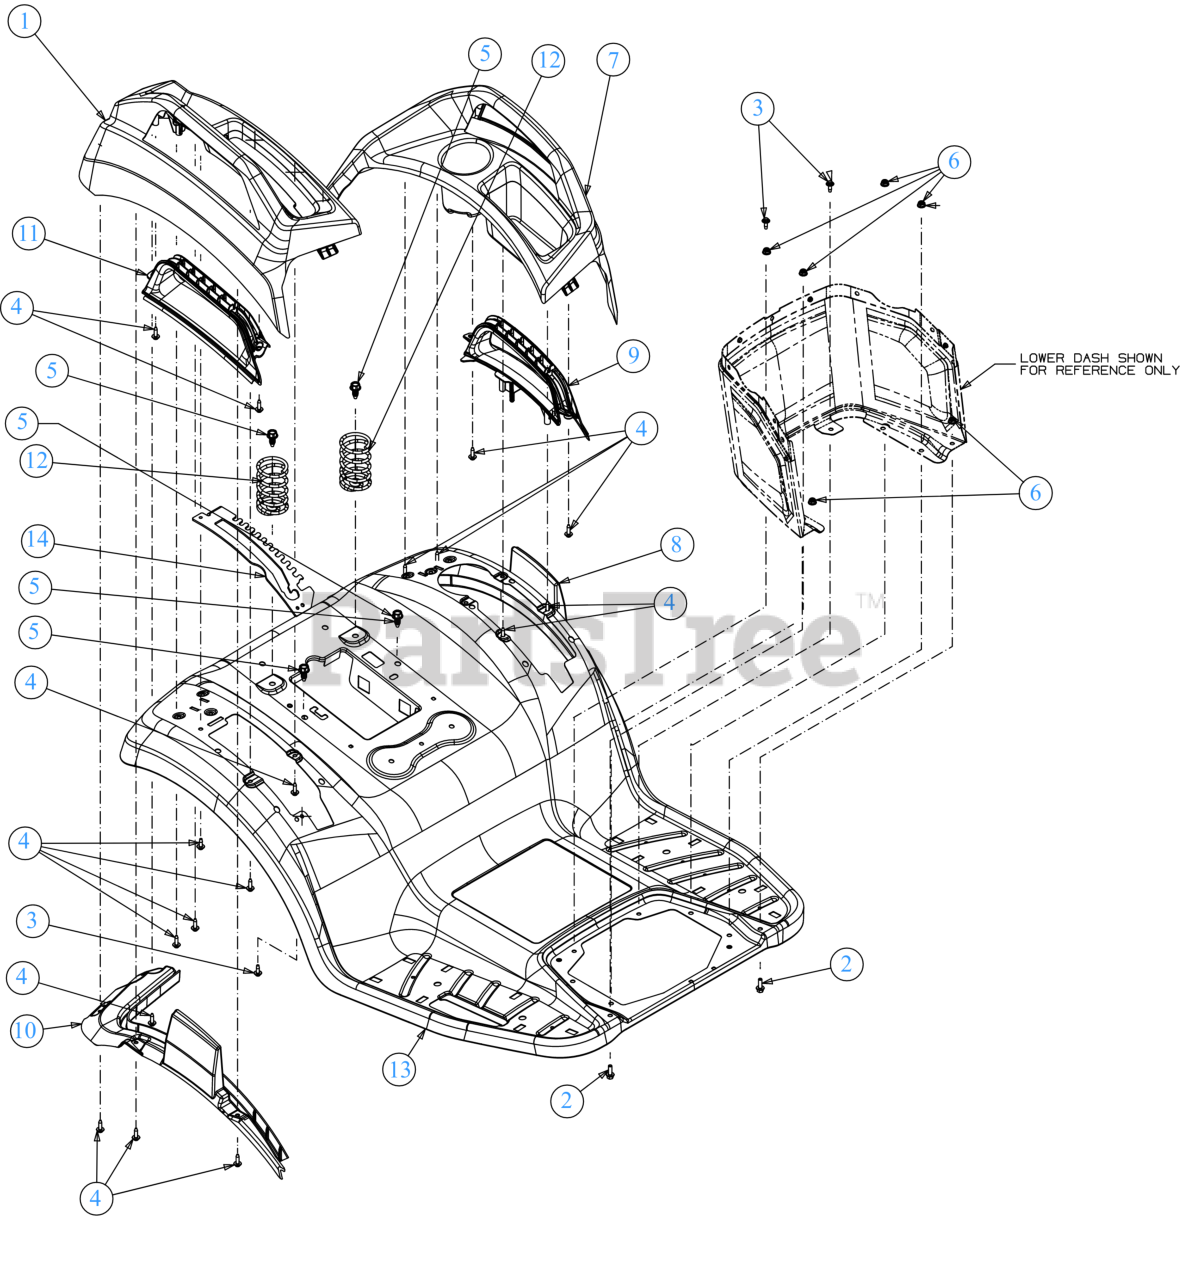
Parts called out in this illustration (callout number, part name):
1	UPPER FENDER COVER (RH)
2	SCREW 1/4-20 x .75 GR5
3	SCREW M6-1 x .625
4	SCREW 1/4-10 x .750
5	HEX SCREW WASH TT 3/8-16 x .875
6	FLANGE LOCK NUT
7	FENDER COVER (LH)
8	FENDER COVER (LH)
9	HANDLE COVER (LH)
10	FENDER COVER (RH)
11	HANDLE COVER (RH)
12	COMPRESSION SPRING 2.18 x 3.65 x .207
